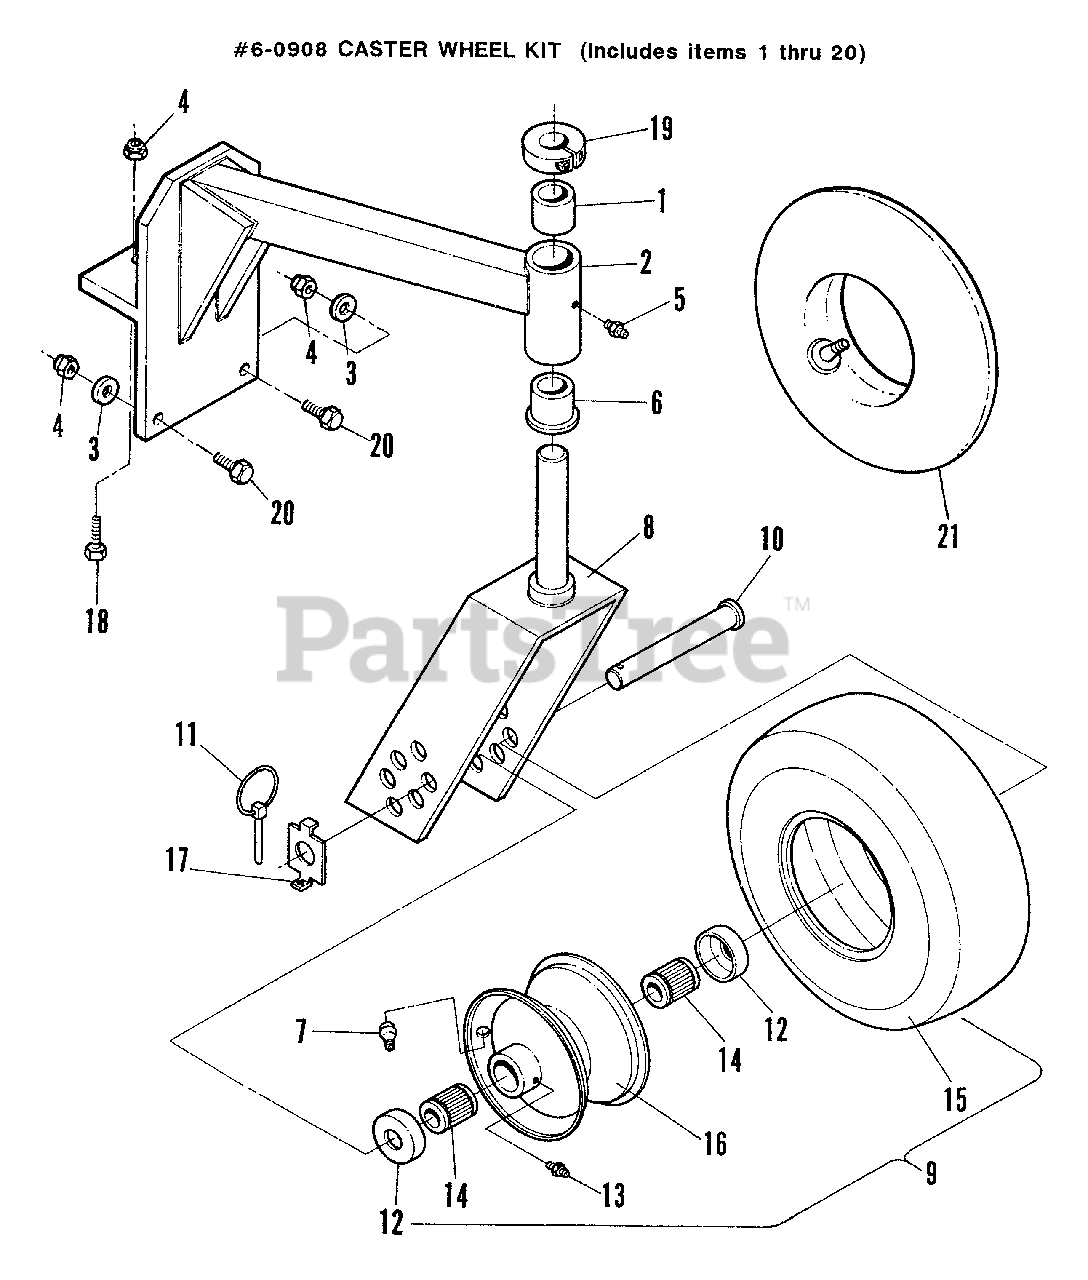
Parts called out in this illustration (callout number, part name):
1	BUSHING, Staight
2	SUPPORT, Caster w/Bushings
3	WASHER, 3/8" Flat
4	NUT, 3/8-16 Hex Flange Lock
5	FITTING, 1/8 N PT Straight Lube
6	BUSHING, Flange
7	STEM, Valve
8	YOKE, Caster
9	TIRE ASSEMBLY
10	AXLE, Caster
11	PIN, 3/16" Dia. Linkch
12	CAP, Wheel Size 1-1/2" I.D.
13	FITTING, 1/4-28, Straight Lube
14	BEARING, Roller
15	TIRE
16	RIM, w/Valve,Cap & Grease Fitting
17	WASHER, Tab
18	BOLT, 3/8-16 x 1-3/4" Hex Head Tap
19	COLLAR, 7/8" Clamp
20	SCREW,3/8-16 x1" Hex Head Cap, Grade 5
21	TUBE, Inner
